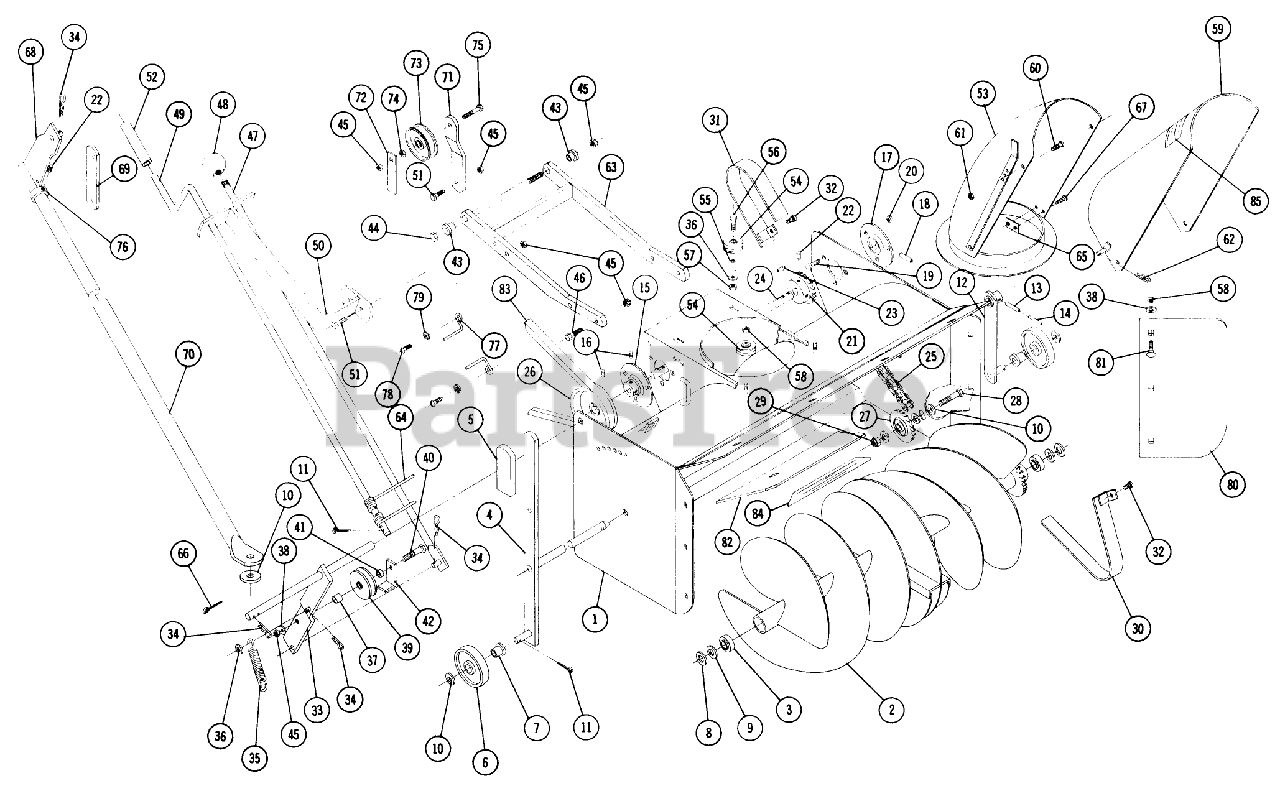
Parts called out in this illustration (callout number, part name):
1	Ass-y Wrapper
5	GRIP
8	Washer
9	WASHER
10	Washer
11	Cotter Pin
13	ROLL PIN 1/4 X 1-1/4
14	Roll Pin 5/32 x 1/4
16	Set Screw
18	PIN-ROLL, SPIROL
19	Bolt Hex 5/16-18 x 3/4
20	Nut-Nylok
22	Set Screw Nylok
23	Key
25	Chain
26	Pulley Drive Shaft
28	Bolt-1/2-13-1 3/4
29	Locknut-1/2-13
34	Hairpin
35	SPRING *R
36	Washer
38	Washer
40	Bolt Hex 3/8-16 x 2 Nylok
41	SPACER
44	Bolt-Hex. 3/8-16 x 8 1/2
46	Bolt 3/8-16 x 7/8
47	Ass-y Rod-Clutch
51	Bolt 3/8-16 x 1
52	Tube
56	Bolt 1/4 20 x 1 1/4
57	Nut-Nylok
58	3/8-16 E.S.
60	Bolt Rd. Hd. 1/4-20 x 1/2
61	Nut, 1/4-20
62	Hairpin
63	Ass-y. Mounting Frame
66	Cotter Pin 3/16 x 1
67	Screw #10-16 x 1/2 Self Tap
71	Bracket-Idler
73	Pully-Idler
74	3/8-16 Jam Nut
75	Bolt, 3/8 16 x 2
78	Bolt Round Head 5/16-24 x 3/4
79	Lockwasher
80	Plate-Side Extension
81	Bolt 3/8-16 x 1
